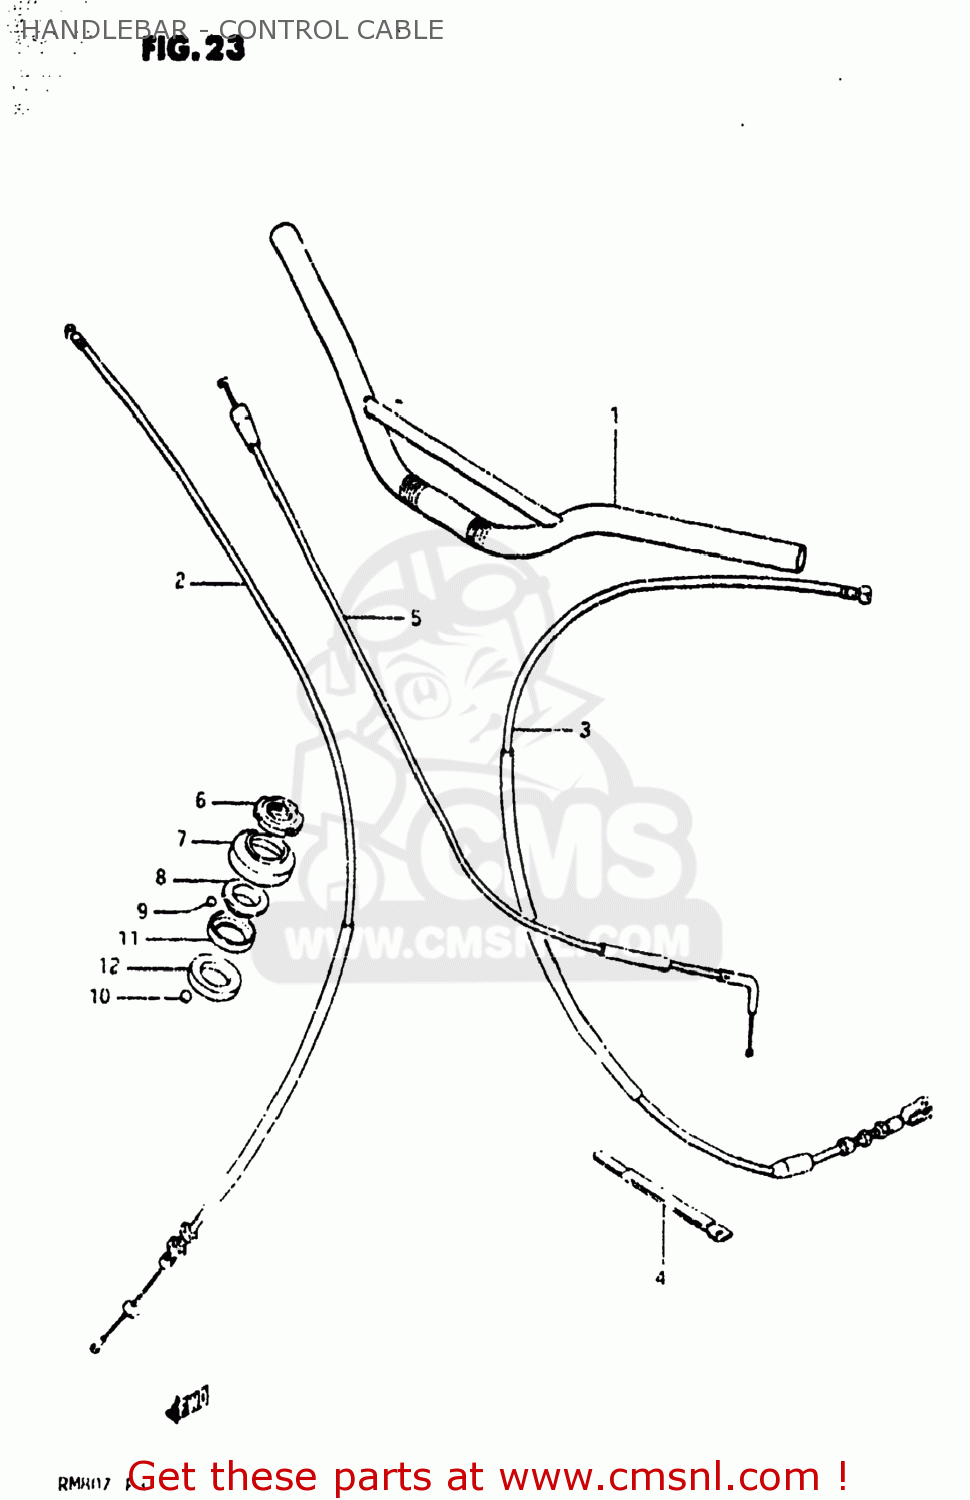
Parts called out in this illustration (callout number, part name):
1	HANDLEBAR
2	CABLE,FRONT BRAKE
3	CABLE ASSEMBLY,CLUTCH
4	CLAMP
5	CABLE ASSEMBLY,THROTTLE
6	NUT,STEERING STEM(25X44X10)
7	DUST SEAL,STEERING UPR
8	RACE,STEERING OUTER UPR
9	BALL
10	BALL
11	RACE,STEERING INNER UPR
12	LACE,STEERING INNER LWR
